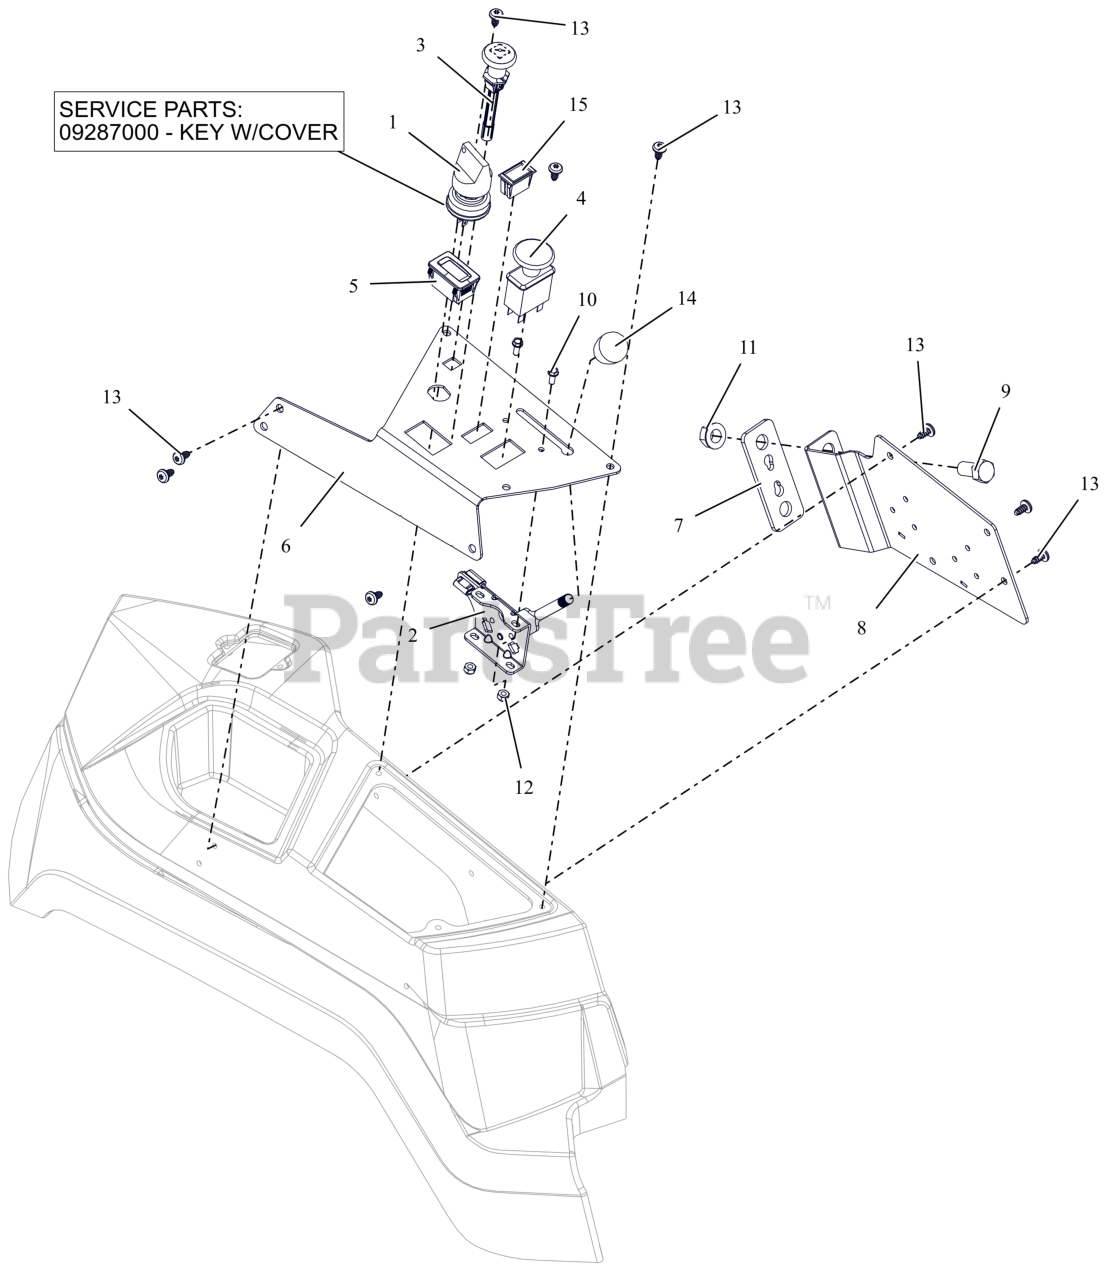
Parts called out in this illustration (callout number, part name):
1	SWITCH, IGNITION
1	KEY, W/ SHIELD
2	CABLE, PRO THROTTLE CONTROL
3	CABLE - CHOKE, SNAP-IN
4	SWITCH, CLUTCH
5	HOUR METER
6	PLATE, APEX CONTROL PANEL
7	PLATE, CONTROL PANEL SPACER
8	BRKT, FENDER/RELAY MOUNTING
9	BLT, HEX .50-13X1.00 G5 ZCC
10	BLT, HWH #10-24X.50 ZCC
11	NUT-LK-TOP-FLG .500-13 GF ZCC
12	NUT-LK-NYL #10-24 G2 ZCC
13	SCR-PAN .25-15X.50 6L H/LZB500
14	KNOB-CONTROL-BLACK .38-16X.50
15	SWITCH,BLANK
